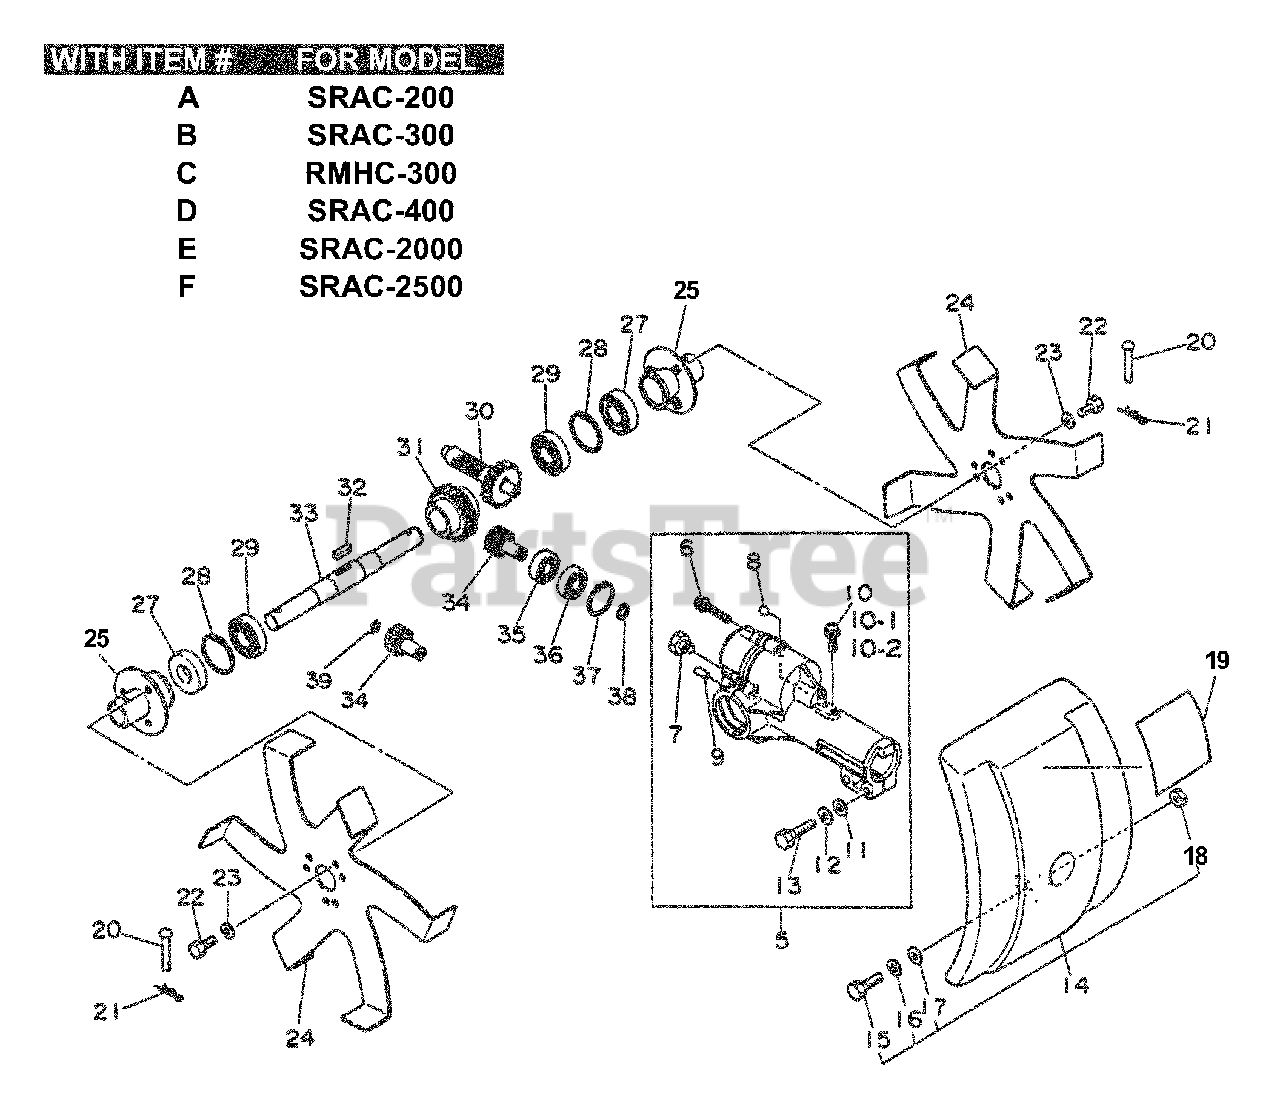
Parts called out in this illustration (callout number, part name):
5	HOUSING, GEAR CASE
5	CASE, GEAR
6	SCREW 4×25
7	BOLT 8×8 SP
8	BALL, STEEL
9	PIN, DOWEL
10	SCREW 5×14
10-1	WASHER, SPRING 5
10-2	WASHER, FLAT 5.5×10×0.8
11	WASHER 6.5×11.5×0.8
12	WASHER, SPRING 6
13	BOLT 6×25
14	SHIELD
15	BOLT 6×20
16	WASHER, SPRING 6
17	WASHER 6.5×11.5×0.8
18	NUT, HEX M6
19	LABEL
20	PIN, CLEVIS
21	PIN, COTTER 5
22	BOLT 6×10
23	WASHER, SPRING 6
25	HUB, TINE
27	SEAL, OIL 17
28	E-RING 30
29	BEARING, BALL 6903
31	WHEEL, WORM
33	SHAFT, WORM WHEEL
34	GEAR
35	BEARING, BALL 609
35	BEARING, BALL 6001
35	BEARING, BALL 6900
36	BEARING, BALL 609
36	BEARING, BALL 6001Z
36	BEARING, BALL 6900
37	RING, SNAP Ø22
37	RING, SNAP 28
38	RING, SNAP Ø9
38	RING, RETAINING - 12
38	RING, SNAP Ø10
39	RING, RETAINING - 7
